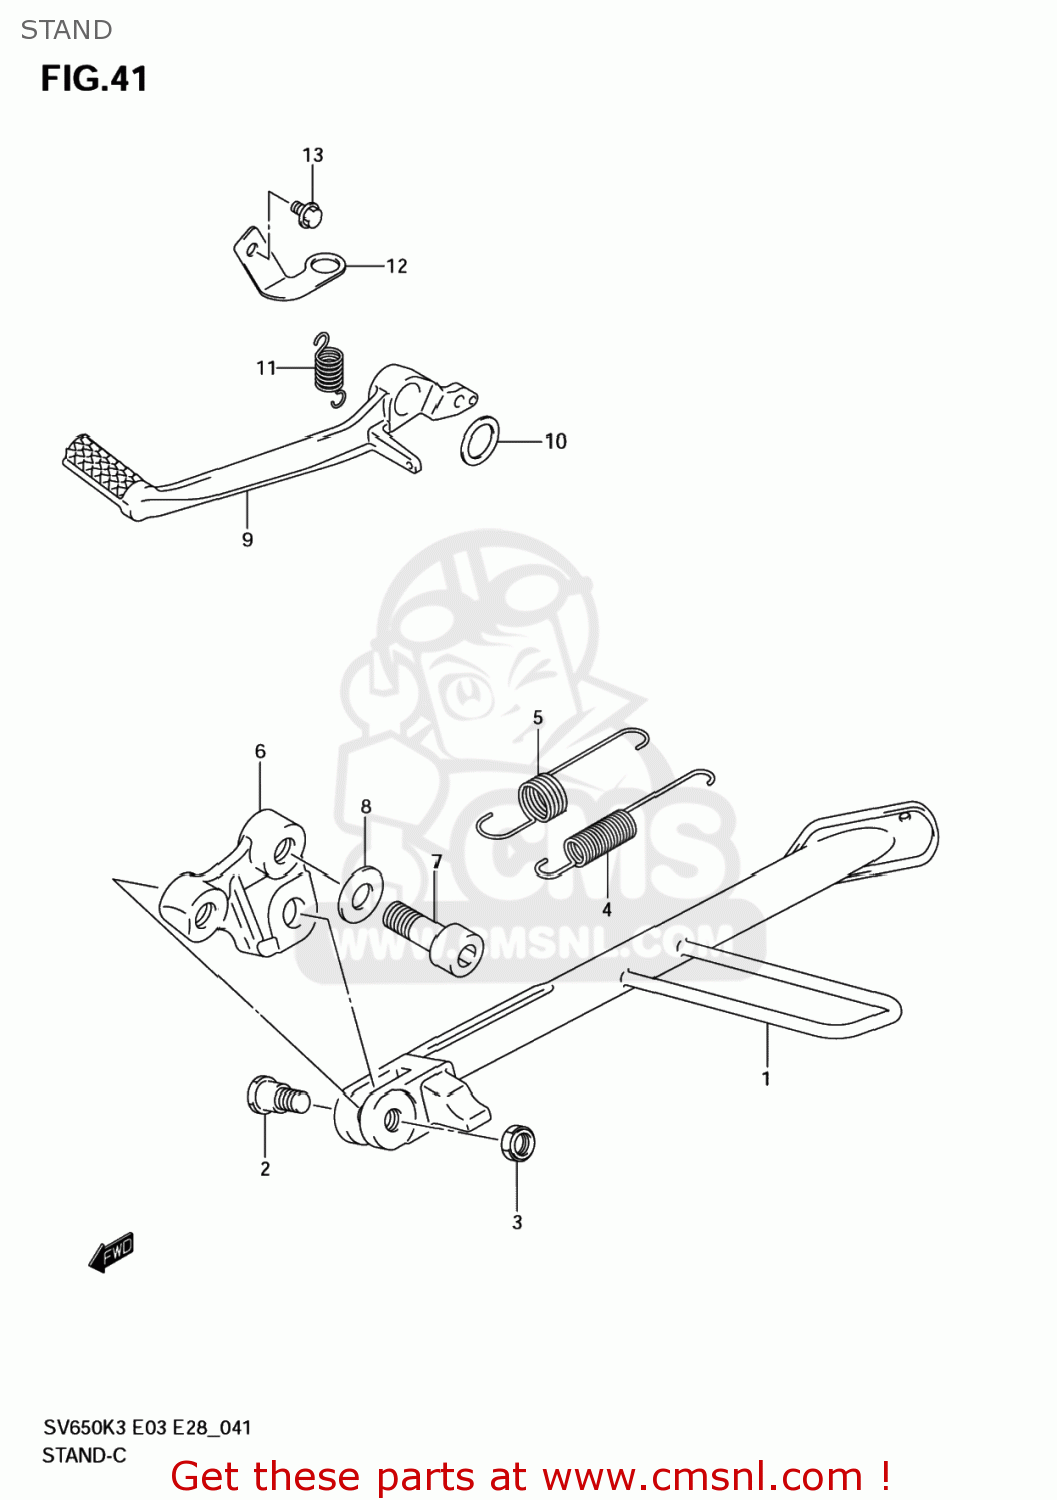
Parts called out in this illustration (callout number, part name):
1	STAND,PROP
2	BOLT(10X34)
3	NUT,PROP STAND
4	SPRING
5	SPRING
6	BRACKET,PROP STAND
7	BOLT(12X35)
8	WASHER(12.5X24X2.6)
9	PEDAL,BRAKE
10	WASHER(18X24X1)
11	SPRING
12	BRACKET,STOP LAMP SWITCH
13	BOLT
